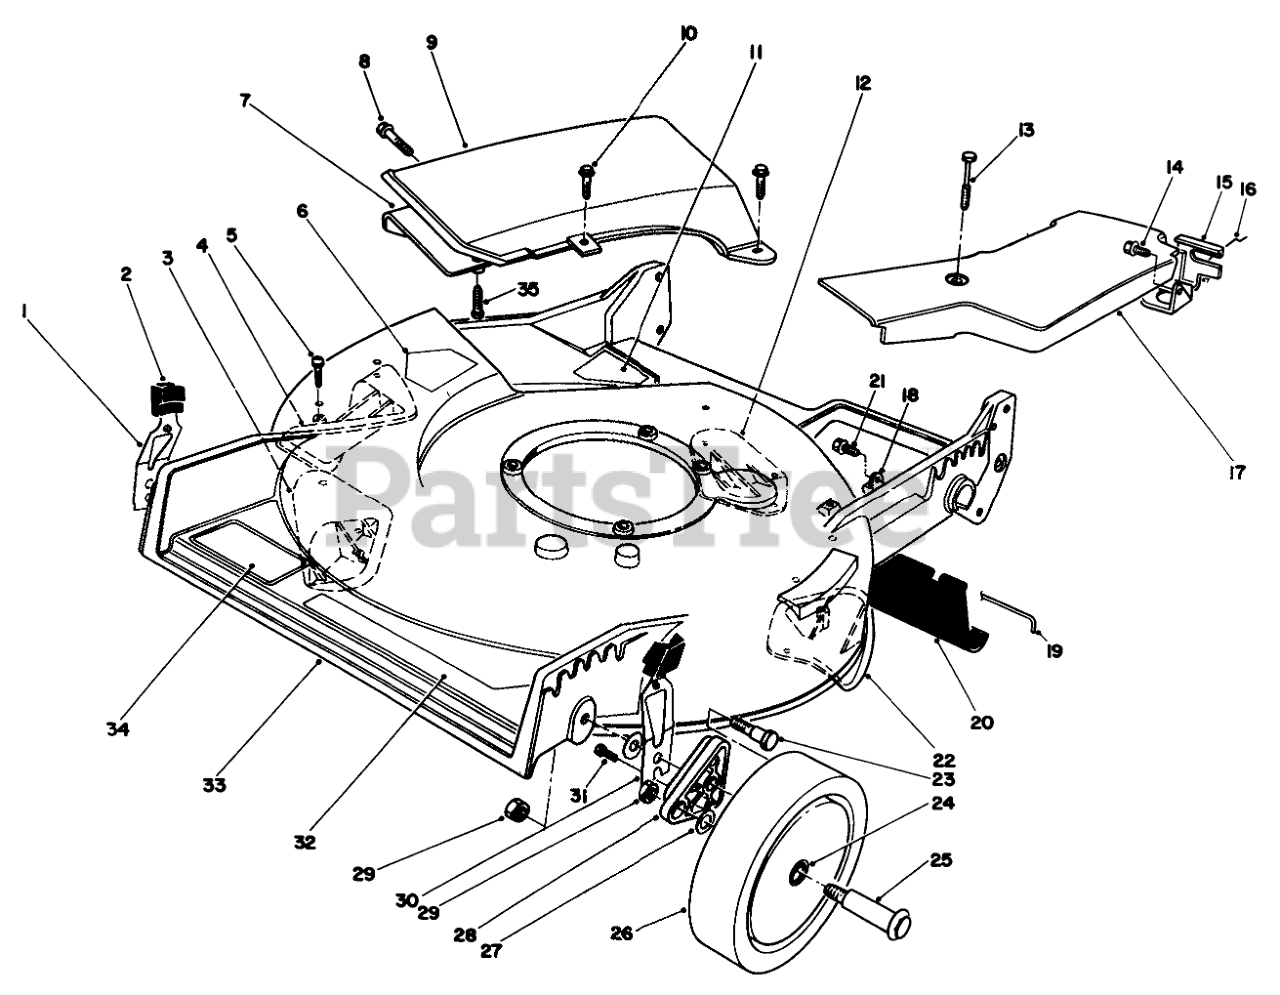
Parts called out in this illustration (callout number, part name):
1	RH SPRING ARM ASSEMBLY
2	KNOB-ARM
3	KICKER
4	KICKER
5	SCREW-PPH
6	DECAL-DANGER
7	Deflector-Recycler
8	SCREW AND WASHER ASM
9	Cover Assembly (Incl. Ref. #7 & 35)
10	SCREW-HWH
11	DECAL - DANGER
12	KICKER
13	SCREW-HHFTF
14	SCREW-HWHTF
15	Bracket-Adj. Trac
16	RETAINER-CABLE
17	BELT COVER
18	CLAMP-CABLE
19	ROD-SHIELD
20	SHIELD-TRAILING
21	SCREW-HWH
22	KICKER
23	SCREW-SHOULDER
24	BUSHING
25	WHEEL BOLT
26	Wheel & Tire Assembly (Incl. Ref. #24)
27	WASHER
28	ARM-PIVOT, FRONT
29	Nut
30	LH SPRING ARM ASSEMBLY
31	SCREW-HWH
32	DECAL - DECK
33	Housing Assembly (Incl. Ref. #3-6, 11, 12, 23, & 32)
34	DECAL
35	Screw-Plastite
